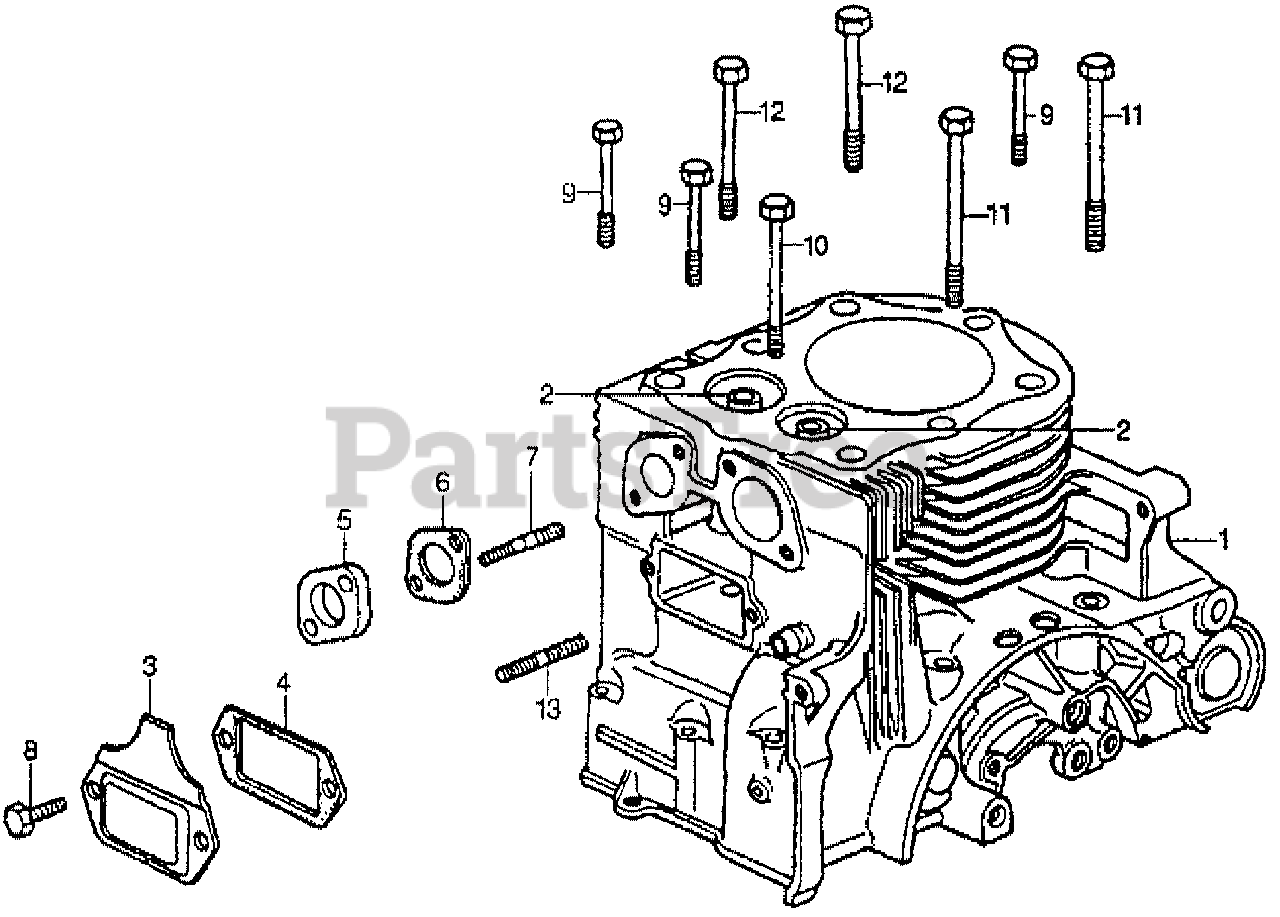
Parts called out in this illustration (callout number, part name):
2	GUIDE, VALVE (OS)
3	COVER, TAPPET (NOT AVAILABLE)
4	GASKET, TAPPET COVER (NOT AVAILABLE)
5	INSULATOR, CARBURETOR
6	GASKET, CARBURETOR INSULATOR (NOT AVAILABLE)
7	BOLT, STUD (8X39) (NOT AVAILABLE)
8	BOLT, HEX. (6X12)
9	BOLT, HEX. (6X63)
10	BOLT, HEX. (6X90)
11	BOLT, HEX. (8X100)
12	BOLT, HEX. (8X80) (SOURCE: VINTAGE PARTS INC.)
13	BOLT, STUD (6X32)
